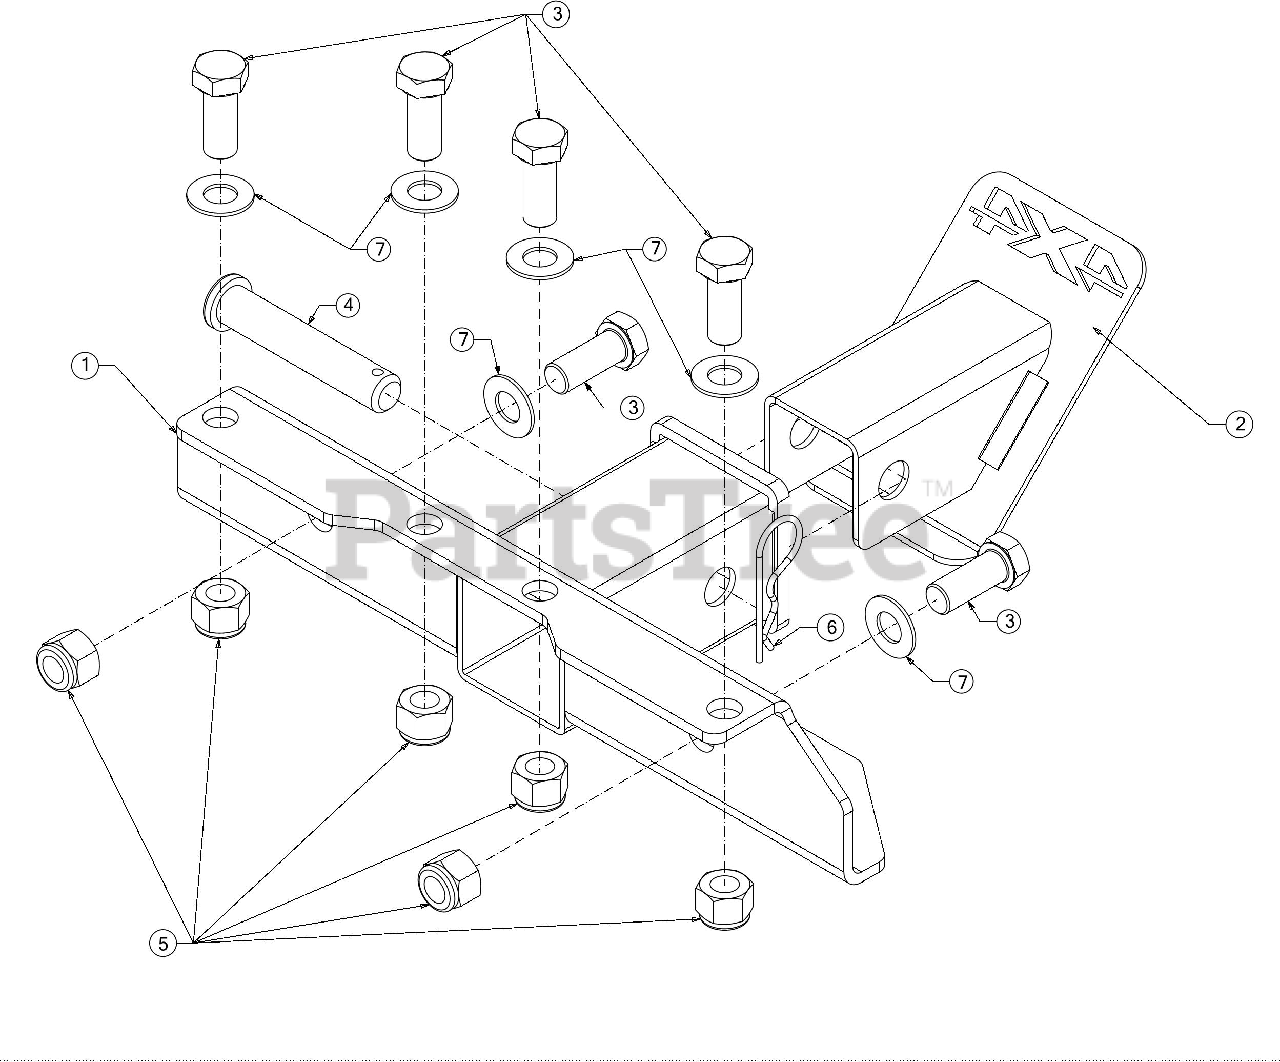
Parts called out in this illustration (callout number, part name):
1	UV HITCH ASSEMBLY
2	4X4 HITCH COVER ASSEMBLY
3	SCREW 1/2-13 x 1.25 GR5
4	CLEVIS PIN
5	HEX LOCK NUT NYLON
6	INTERNAL COTTER PIN
7	FLAT WASHER .510 x 1.00 x .060
